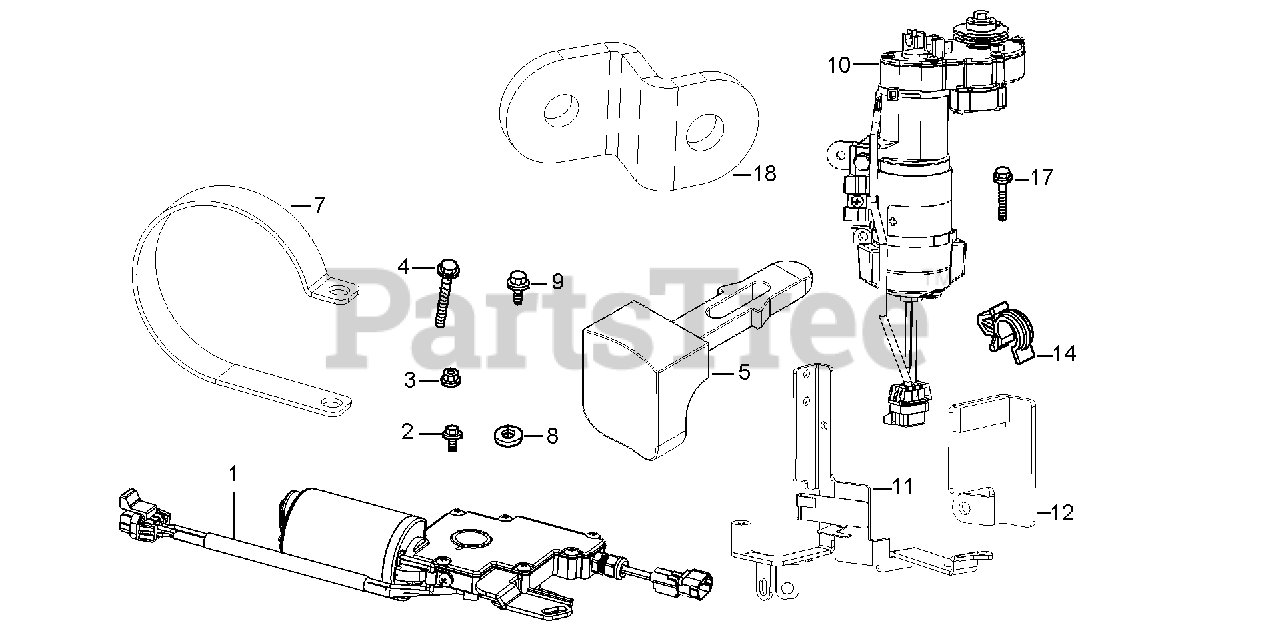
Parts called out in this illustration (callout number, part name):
1	GEAR ACTUATOR, IST
2	BOLT, FLANGE (6X20)
4	BOLT, LOCK SS (M6X50)
5	CPA-DELPHI MP (150)
6	BRACKET, SHIFT ACT
7	CLAMP, SHIFT ACT
8	WASHER, PLAIN (6MM)
9	BOLT, FLANGE (6X14) (CT200)
10	THROTTLE ACT, IST
11	BRACKET, THROTTLE ACT
12	BRACKET, HEAT SHIELD
13	BOLT, FLANGE (6X14) (CT200)
14	HOLDER, ROD (A)
15	SCREW, SHCS (6X25) (NOT AVAILABLE)
16	WASHER, LOCK (NOT AVAILABLE)
17	BOLT, FLANGE (6X28)
18	BRACKET THROT STAB
